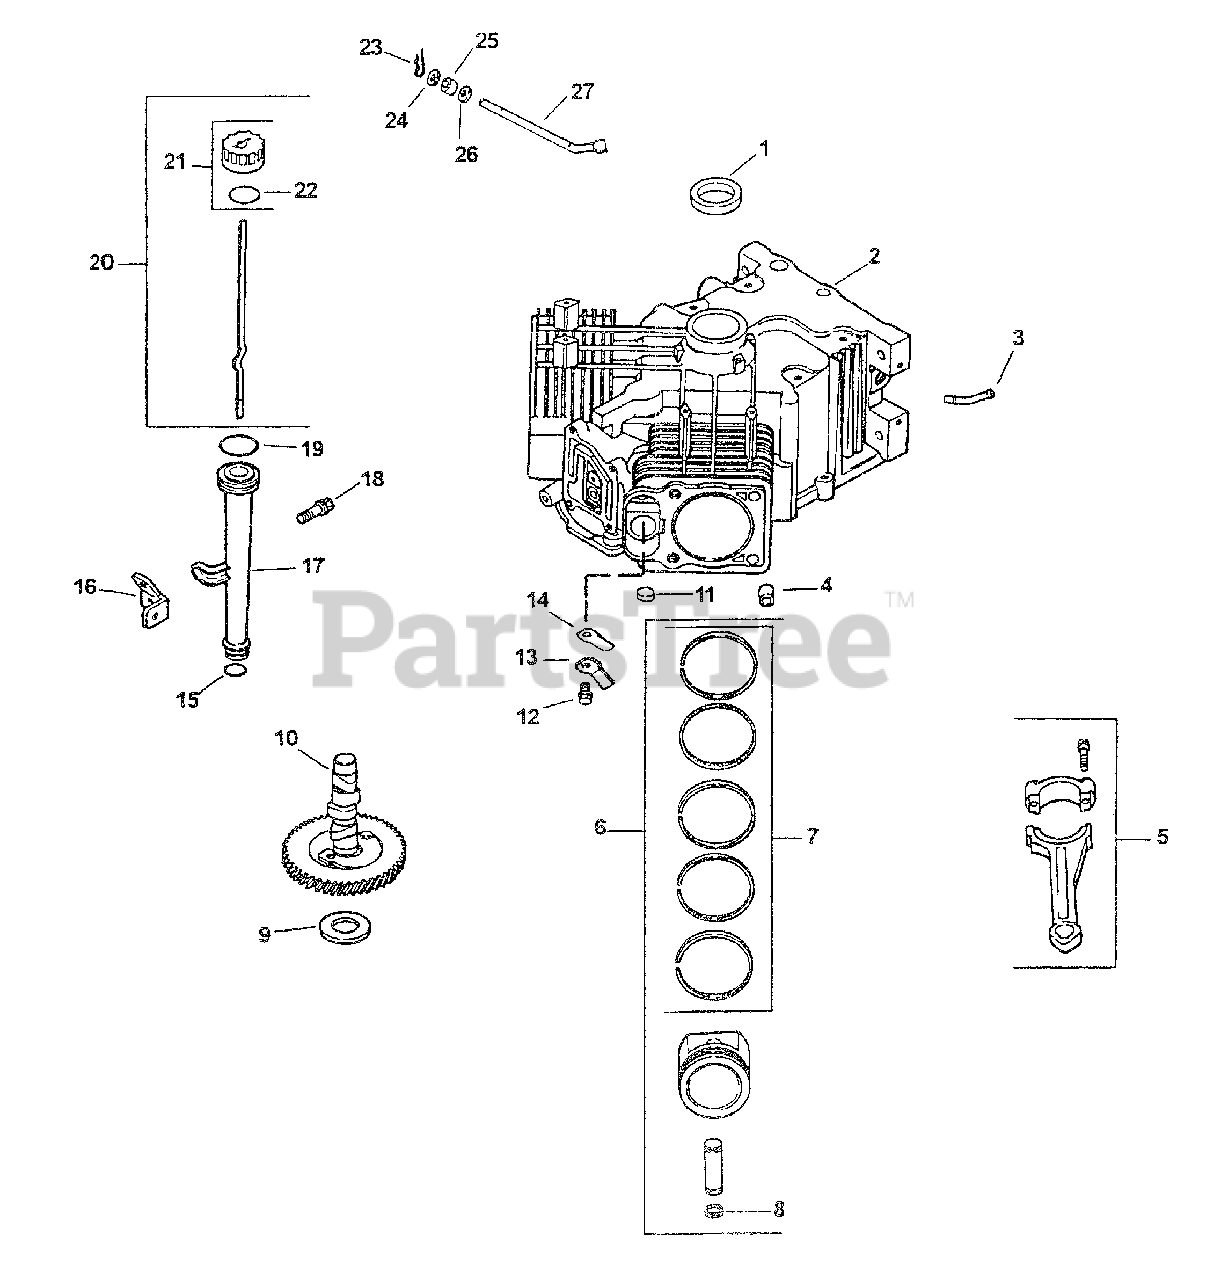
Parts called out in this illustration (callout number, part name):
1	Seal, Oil Front
2	Crankcase
4	Pin, Dowel Locating
5	Connecting Rod
6	Piston w/Ring Set
7	Ring Set
8	Retainer, Piston Pin
9	Shim, Camshaft (A.R.) (White) .02725-.02875
10	Camshaft
11	Plug, Cup
12	Screw, Hex Flange
13	Retainer, Reed
14	Reed, Breather
15	O-Ring, Lower Oil Fill Tube
16	Bracket, Oil Fill Tube
17	Tube, Oil Fill
18	Screw, Hex Flange
19	O-Ring, Upper Oil Fill Tube
20	Dipstick Assembly
21	Kit, Oil Fill Cap
22	O-Ring, Dipstick
24	Washer, Plain 6mm
25	Seal, Governor Cross Shaft
26	Washer, Plain 1/4"
27	Shaft, Governor Cross
